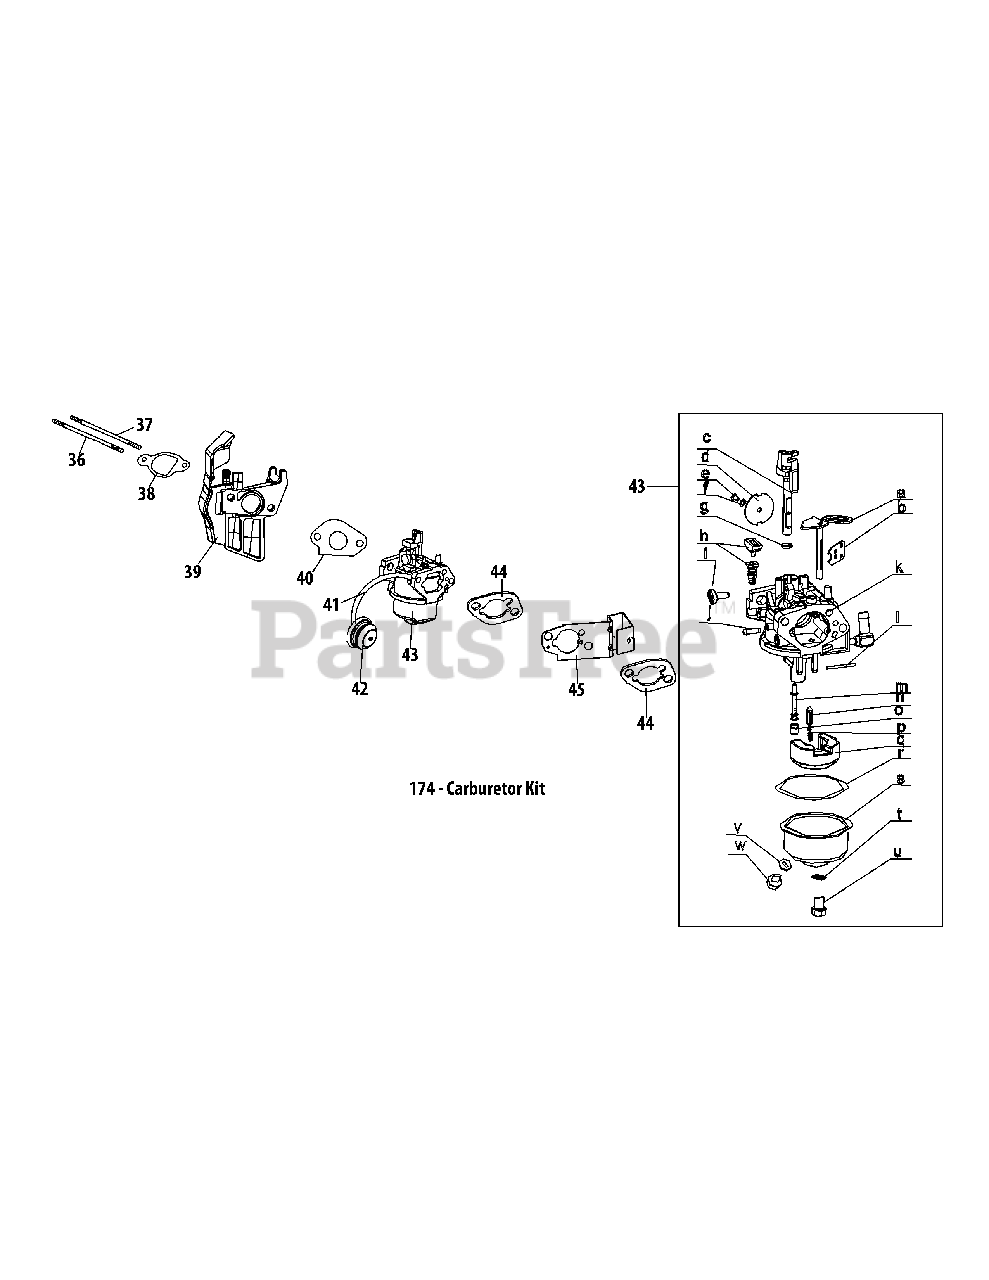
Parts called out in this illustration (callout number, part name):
36	Stud M6×117
37	Stud M6×105
38	Carburetor Insulator Gasket
39	Carburetor Insulator
40	Carburetor Gasket
41	Primer Hose
42	Primer Assembly
43	Carburetor Assembly
44	Carburetor Gasket Plate
45	Choke Control
174	Carburetor Kit
